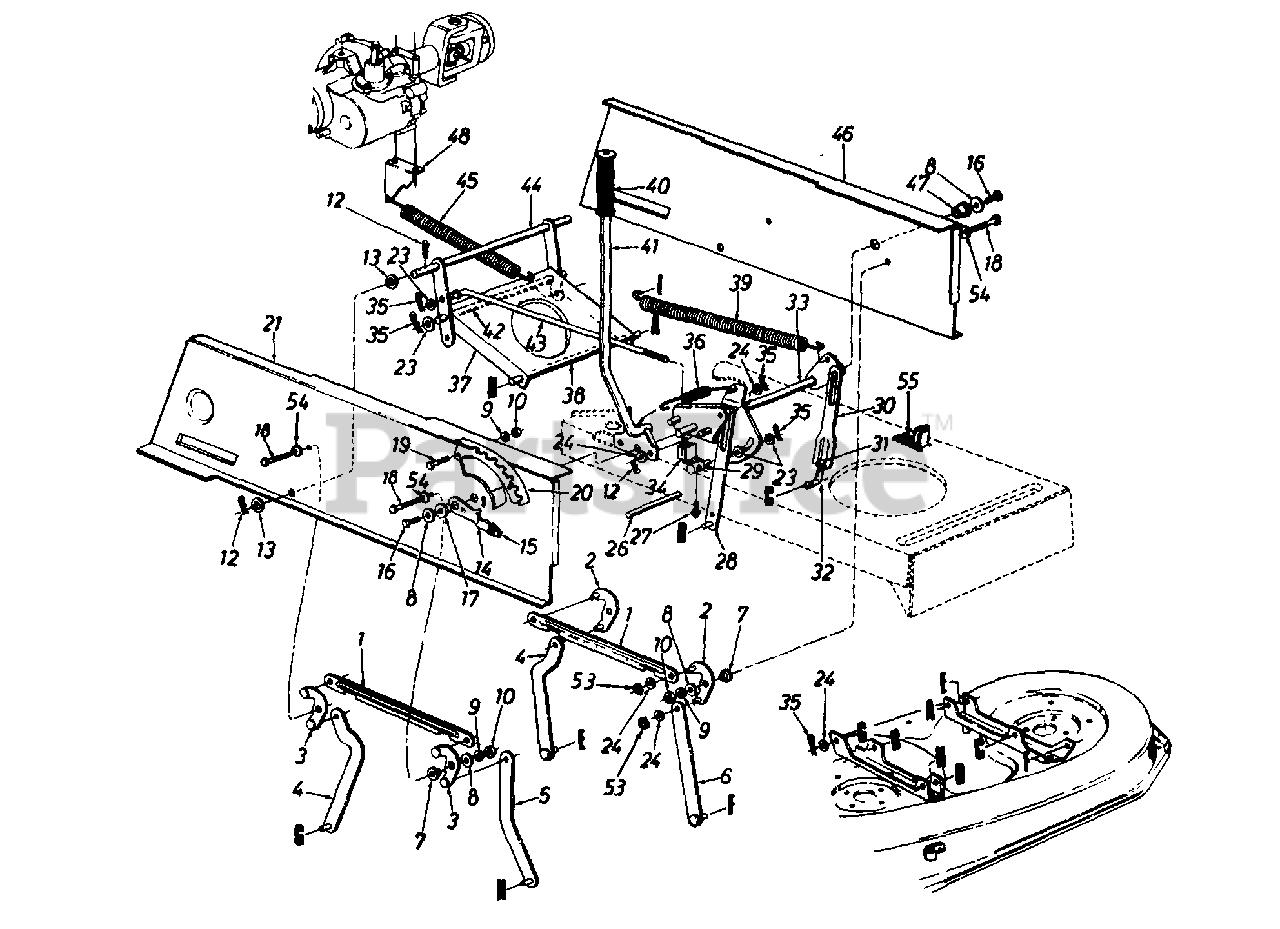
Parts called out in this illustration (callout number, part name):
3	Pivot Link Ass'y. - R.H.
7	Shld. Spacer .318" I.D.
8	Fl-Wash. .344" I.D. x 1.125"
9	L-Wash. 5/16" I.D.
10	Hex Nut 5/16-18 Thd.
12	Cotter Pin 1/8" Dia.
13	Fl-Wash. .635" I.D. x 1.0" O.D.
14	Height Adj. Stop Lever Ass'y.
15	Knob
16	Hex Wash .TT-Tap Scr. 5/16-18 x .75" Lg.
17	Flange Brg. .63" I.D.
18	Hex Wash. Hd. Scr. 5/16-18 x .875" Lg.
19	Hex Bolt 5/16-18 x .75" Lg.
20	Index Brkt.
21	Upper Frame - R.H.
23	Fl-Wash. .385" I.D. x .87" O.D.
24	Fl-Wash. .531" I.D. x .93" O.D.
26	Running Board Rod
27	Truss Mach. Scr. #10 x .5" Lg.
31	Hex Nut 1/2-20 Thd. (Gr. 5)
32	Lift Link Adjuster
33	Lift Shaft Ass'y.
34	Safety Switch (Deck)
35	Inter. Cotter Pin 3/8" Dia.
36	Extension Spring
39	Extension Spring
40	Grip (Lift Handle)
43	Disengagement Rod
46	Upper Frame - L.H.
47	Flange Brg. .632" I.D.
53	"E"-Ring
54	Bell-Wash. .325" I.D.
55	Spring Switch
